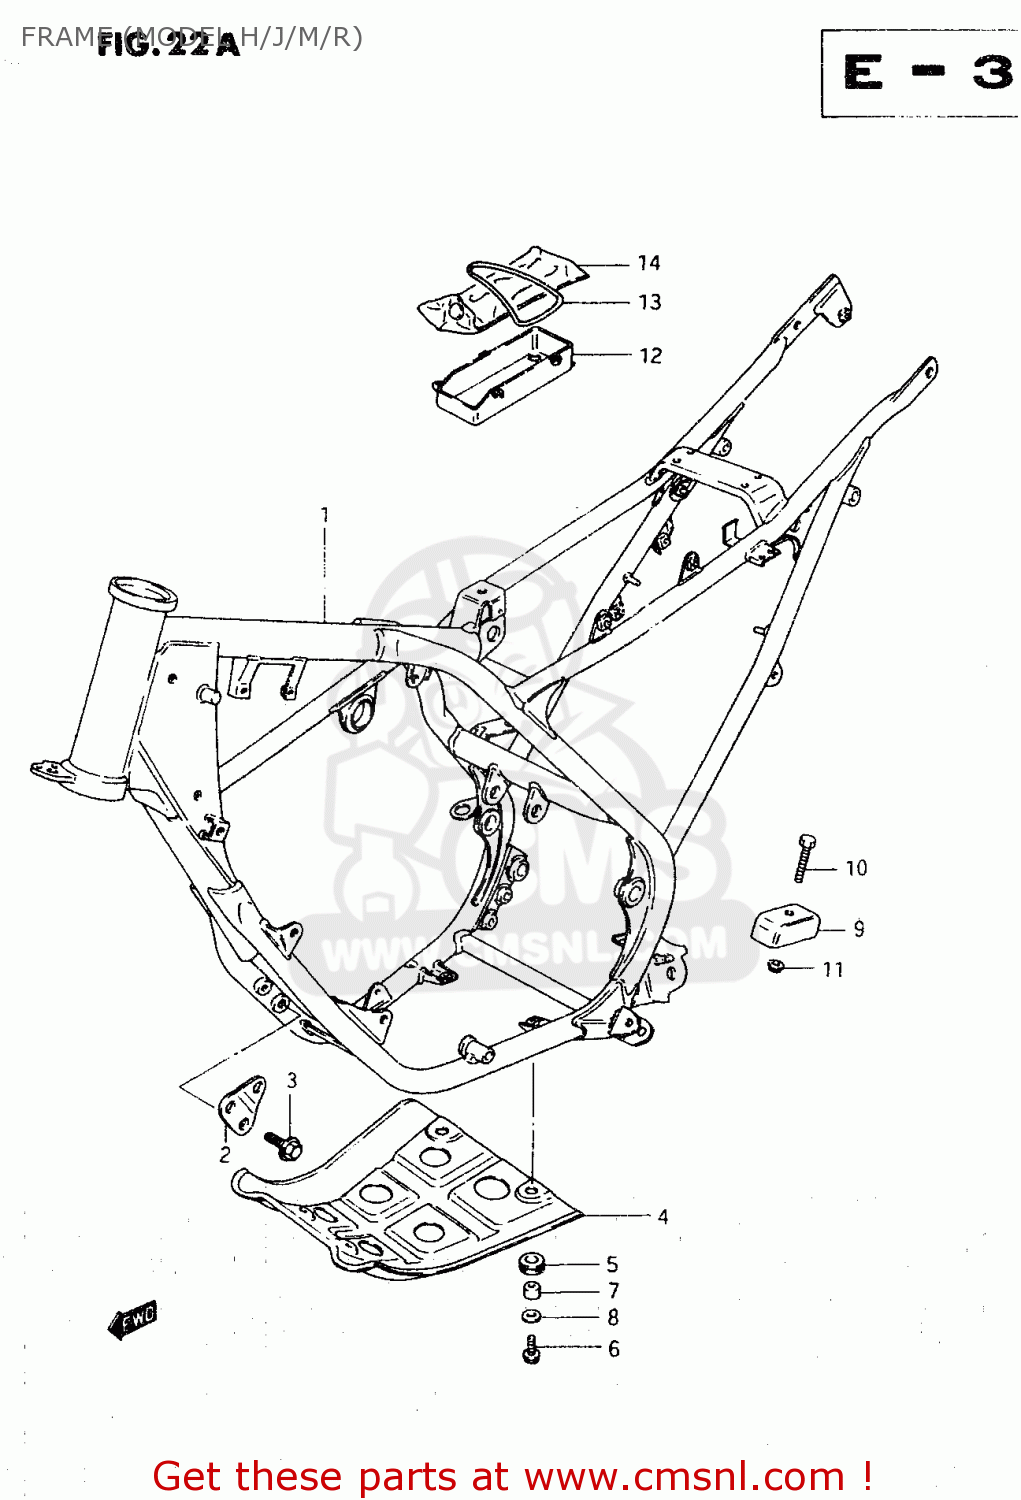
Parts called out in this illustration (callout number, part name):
1	FRAME (BLUE)
2	PLATE,ENG MTG
3	BOLT
4	PROTECTOR, ENGINE
5	CUSHION
6	BOLT
7	SPACER (6X9X5)
8	WASHER(6.5X18X1)
9	GUIDE,CHAIN CONTROL
10	BOLT
11	NUT
12	HOLDER, TOOL
13	O RING(D:3.53,ID:69.44)
14	TOOL ASSY
